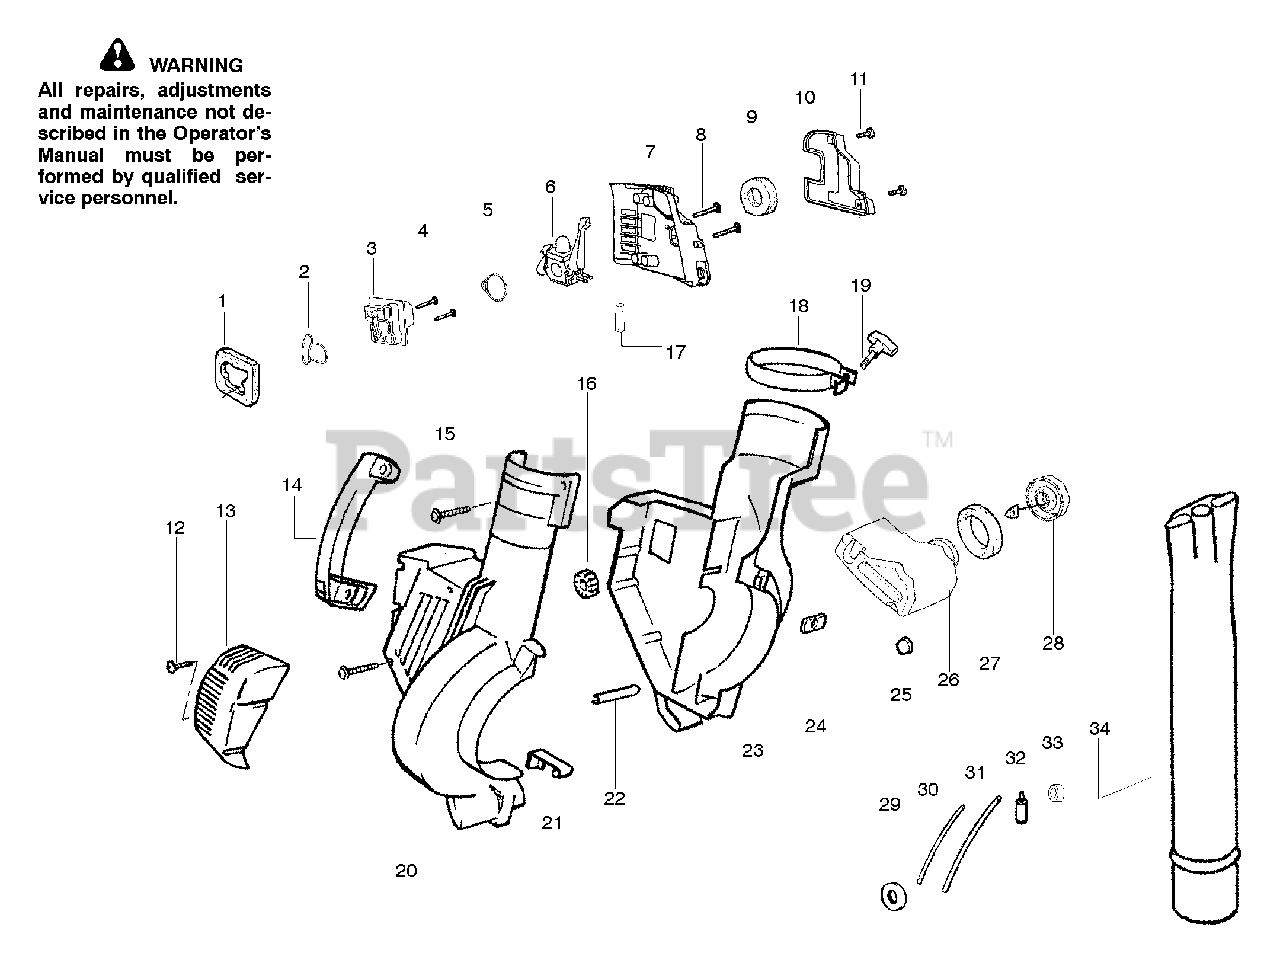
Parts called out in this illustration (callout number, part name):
1	Air Dam (kit)
2	Gasket-Adapter (kit)
3	Carburetor Adaptor
5	Gasket-Carburetor (kit)
6	Kit-Carb Ass'y. (C1Q-W11)
8	Screw-Carb.
9	Filter-Air
10	Cover-Air Filter
11	Screw-Air Box Cover
13	Assy-Muffler Cover
16	Isolator
17	Foam 25.4mm (kit)
18	Clamp-Blower Tube
19	Knob-Tube Clamp
20	Housing-Right
21	Spring-Cover Latch
22	Guide-Starter Rope
23	Housing-Left
25	Isolator-Crankcase
26	Assy-Fuel Tank
27	Gasket-Fuel Tank
28	Fuel Cap w/Retainer
29	Grommet-Shroud
30	Kit-Line Carb/Purge
31	Kit-Line Tank/Purge
32	Assy-Fuel Pick-up
33	Grommet-Fuel line (kit
34	Tube - Blower BV - 1850
34	Tube - Blower BV - 2000
